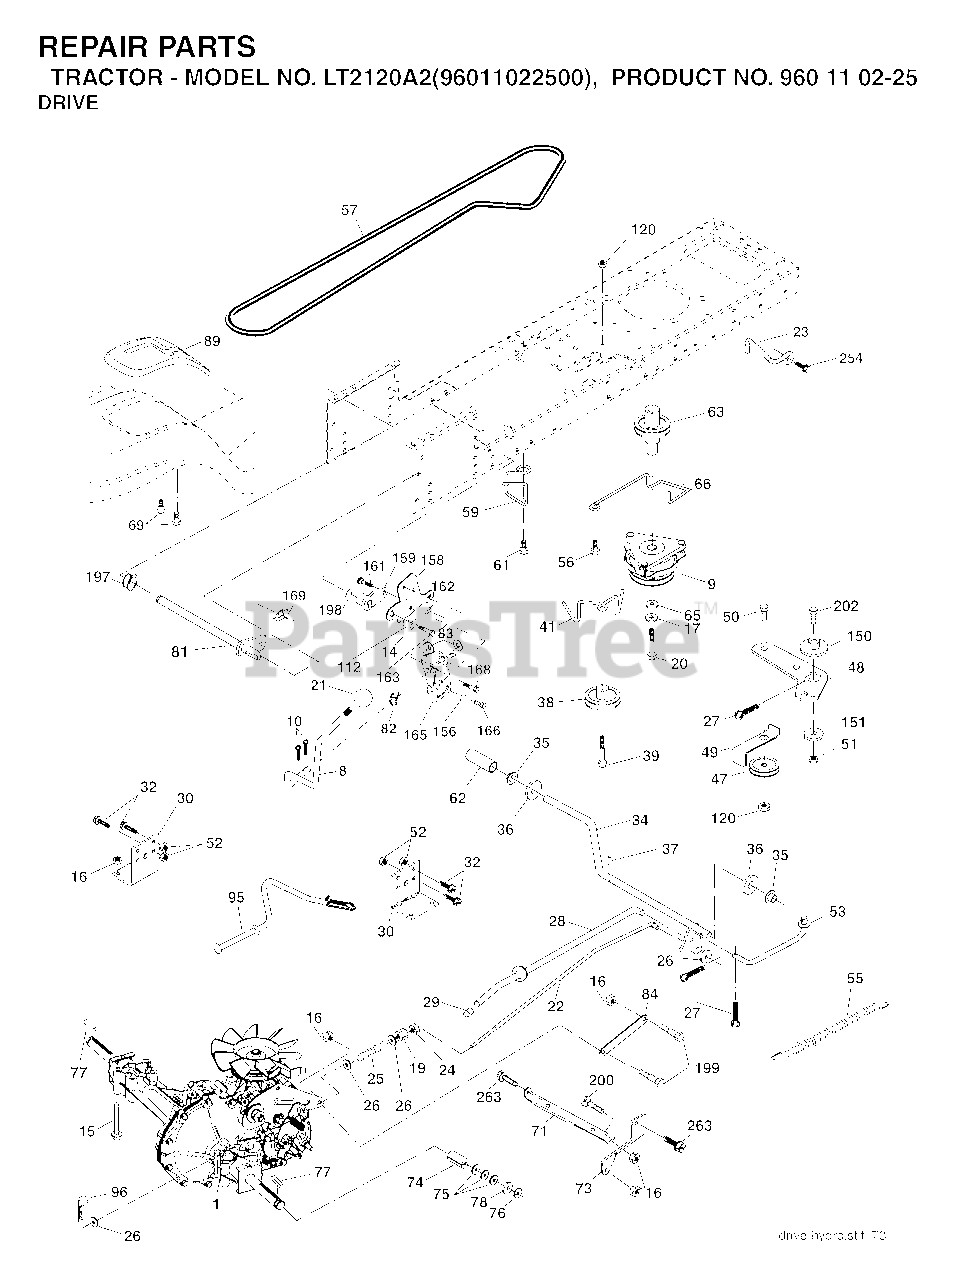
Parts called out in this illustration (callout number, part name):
8	ROD.SHIFT.FENDER.ADJ.STLT
9	CLUTCH
10	PIN COTTER
14	LOCKWASHER
15	BOLT HEX 5/16-18 GR 5
16	NUT.71038.31-18.HEX.NYLOCK
19	NUT
20	BOLT HEX 7/16-20X4-1/4"
21	PISTOL KNOB
22	ROD BRAKE HYDRO
23	BRACKET, ANTI-ROTATION
24	NUT
25	SPRING ROD LT
27	COTTER PIN
28	ROD, PARKING BRAKE
29	PLUNGER CAP
30	BRKT, TRNSXLE MNT 20"
32	BOLT
34	SHAFT, FOOT PEDAL
35	BEARING.NYLON
36	WASHER LT
37	DRIVE PIN
38	PULLEY IDLER COMPOSITE
41	KEEPER, BELT IDLER
47	IDLER PULLEY
48	BELLCRANK, CLUTCH
49	RETAIN BELT
50	BOLT.3/8-16X1.50
51	LOCKNUT
52	LOCKNUT
53	LINK.CLUTCH.7.66.2005
55	SPRING, RETURN LT
56	SCREW.3/8-16
57	DRIVE BELT, LTH & YTH TRACTORS
59	KEEPER, BELT CENTER
61	SCREW 3/8-16X.875
62	PEDAL COVER T
63	PULLEY- ENGINE
65	LOCKWASHER
66	KEEPER BELT ENGINE
69	SCREW.HI-LO.CONSOLE
71	STRAP TORQUE LH HYDRO
73	STRAP TORQUE RH HYDRO
74	SPACER AXLE
76	E-RING LT
77	SQUARE KEY
81	SHAFT ASM CROSS TAPERED
82	SHIFT SPRING
83	WASHER
84	LINK TRANSAXLE
95	CONTROL ASM. BYPASS HYDRO
96	RETAINER M
120	NUT LOCK FLG 3/8-16 UNC
150	SPACER, RETAINER
151	WASHER 12/32X2X10GA
156	WASHER.SRRTD.5/16
158	BRACKET
159	HUB.SHIFT
161	BOLT
162	NUT.CROWNLOCK.1/4
165	RP BRACKET
168	BOLT.SHOULDER.5/16-18X
169	PLATE.FASTENING.CROSS.SHAFT
197	NYLINER SNAP 5/8" ID
198	WASHER.NYL.7/8IDX.105"HYD CR
199	BOLT SHOULDER 5/16-18 UNC
200	BOLT
202	BOLT.3/8-16X1.50
254	SCREW 3/8-16X1
263	SCREW, 3/8-16X3/4
